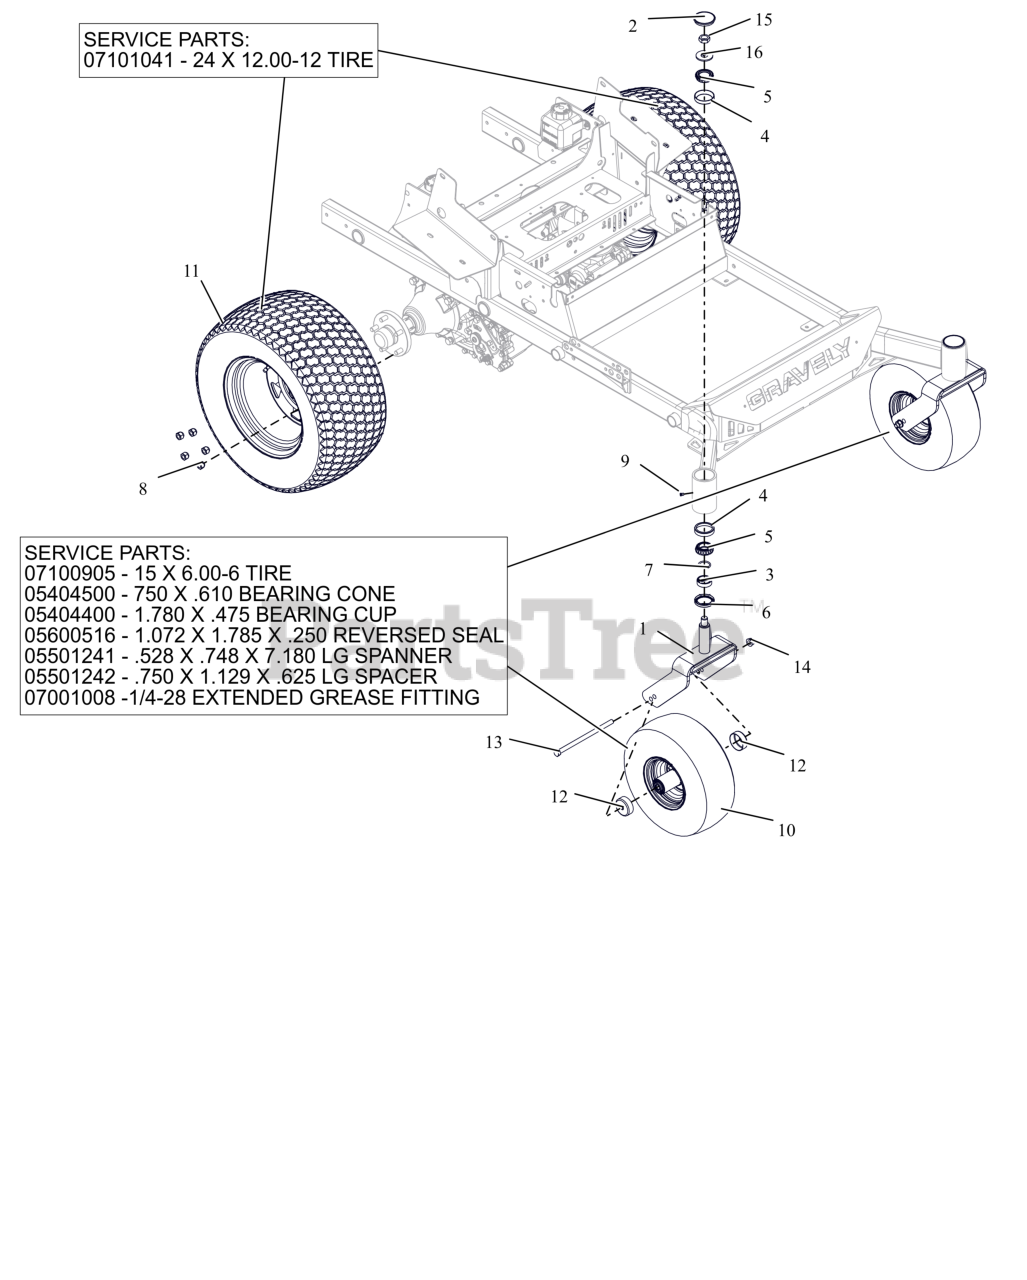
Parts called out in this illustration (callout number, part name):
1	CASTER FORK WMT - RED
2	CAP, DUST
3	SPCR, FRONT CASTER FORK
4	BRG-CUP 2.328X.465
5	BRG-CONE 1.25X.66
6	SEAL, OIL 1.75 X 2.332 X .312
8	NUT, WHEEL .50-20 ZCC
9	FTG, .25-28 FLUSH MNT GREASE
10	ASM, WHL/TIRE 15X6.00-6 SMOOTH
10	TIRE, 15X6-6 SMOOTH
10	BRG-CONE .750X.61
10	BRG-CUP 1.781X.475
10	SEAL,1.072X1.785X.250 REVERSED
10	SPANNER, .528X.748X7.18 LG
10	SPACER, .750X1.129X.625 LG
10	GREASE FITTING 1/4-28 EXTENDED
11	ASM, WHL/TIRE 24X12.00-12 K500
11	TIRE, 24 X 12.00-12
12	SHIELD, WHEEL BEARING
13	BLT, HEX .50-13X9.00 G5 ZCC
14	NUT-LK-TOP-FLG .500-13 GF ZCC
15	NUT, JAM-TOPLOCK .750-16 ZCC
16	WSHR-FL-STL 0.812X2X0.148 ZCC
